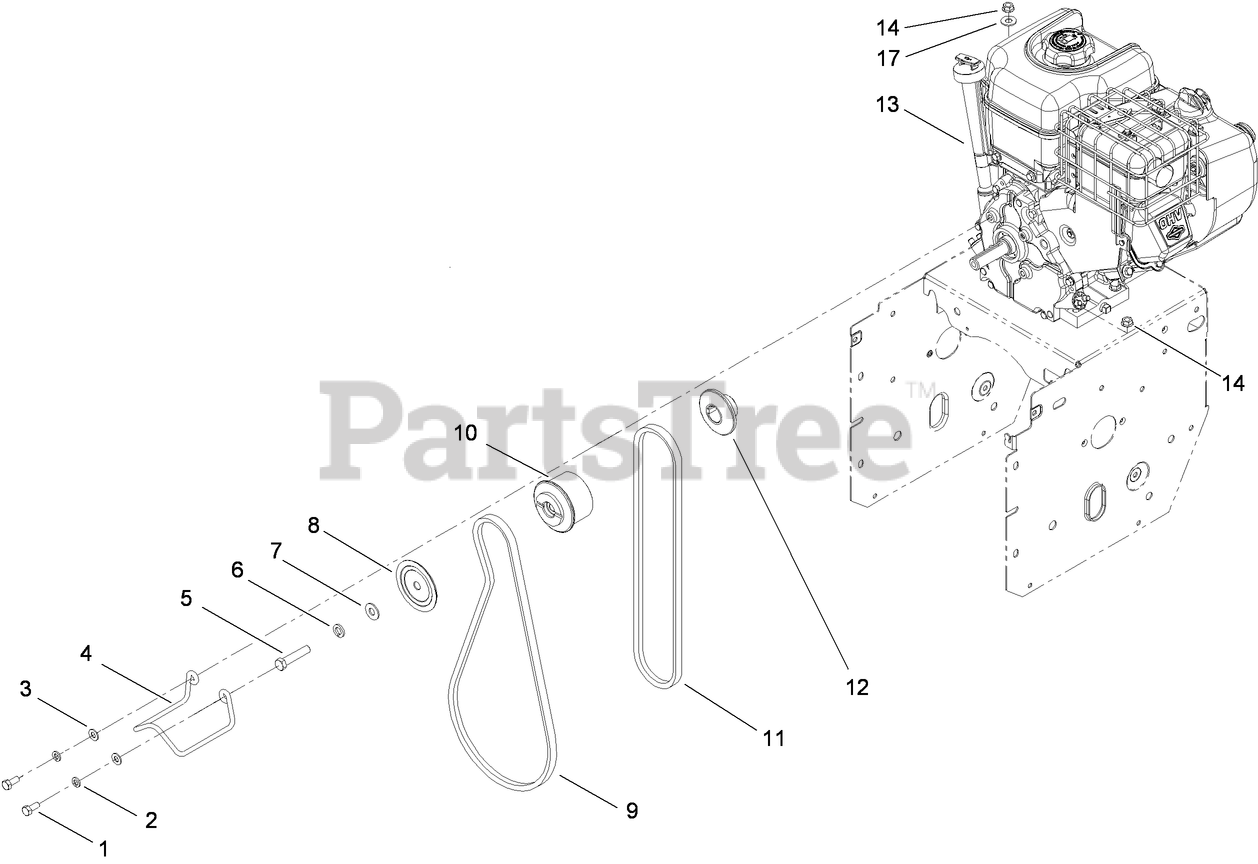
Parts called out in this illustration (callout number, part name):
1	SCREW-HH
2	WASHER-LOCK
3	WASHER-PLAIN
4	GUIDE-BELT
5	SCREW-HH
6	WASHER-LOCK
7	WASHER-FLAT
8	SHEAVE-HALF, IMPELLER
9	BELT-V
10	PULLEY-ENGINE, CENTER
11	V BELT-TRACTION
12	SHEAVE-HALF, TRACTION
14	NUT-HF
17	WASHER-FLAT
